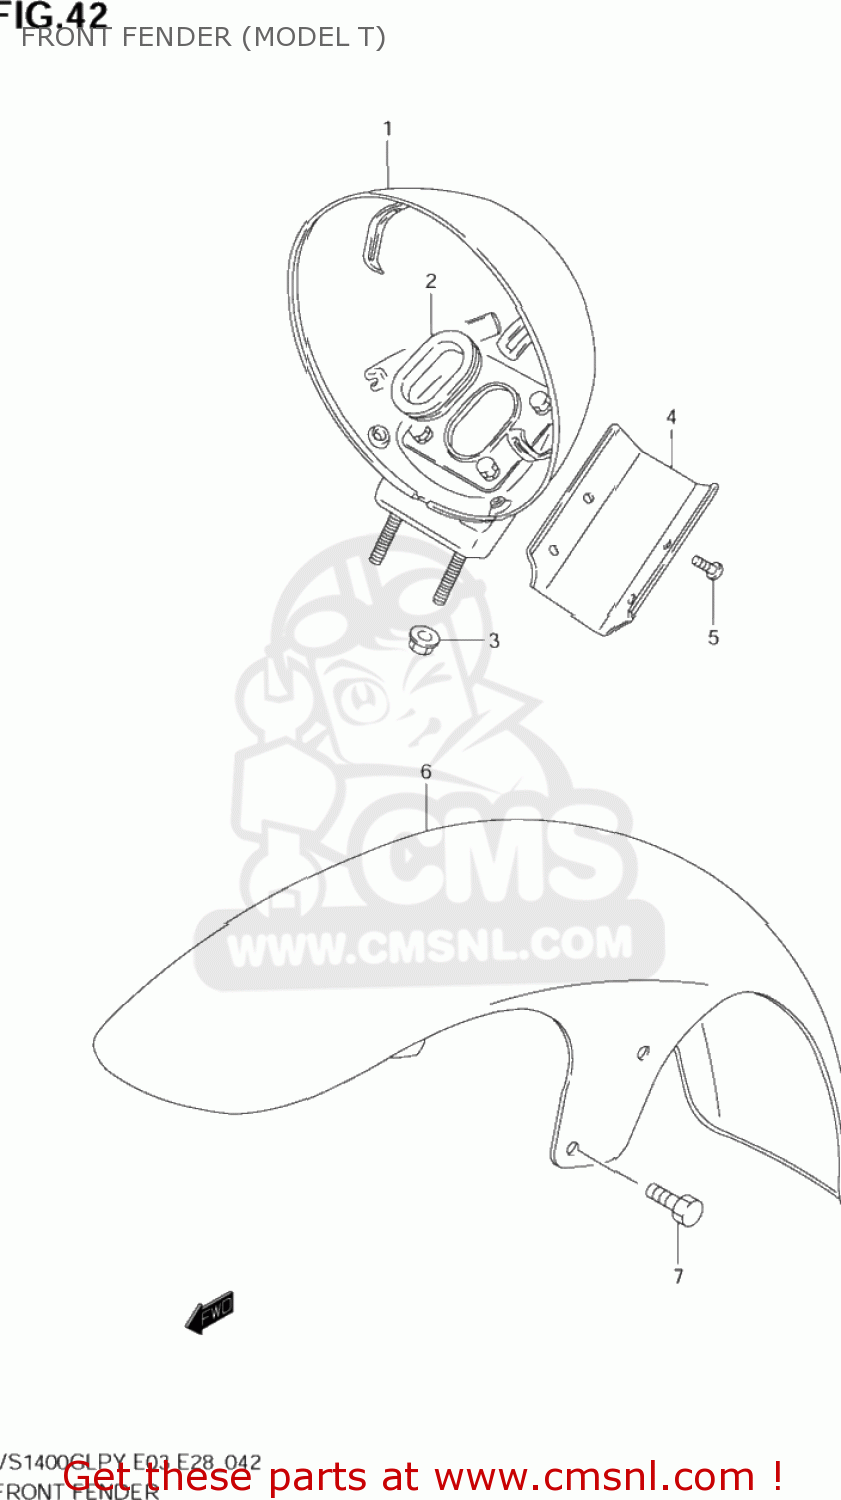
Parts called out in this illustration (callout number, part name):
1	HOUSING,HEADLAMP
2	GROMMET
3	NUT
4	COVER,HEADLAMP HSG
5	SCREW
6	FENDER COMP,FRONT
7	BOLT
